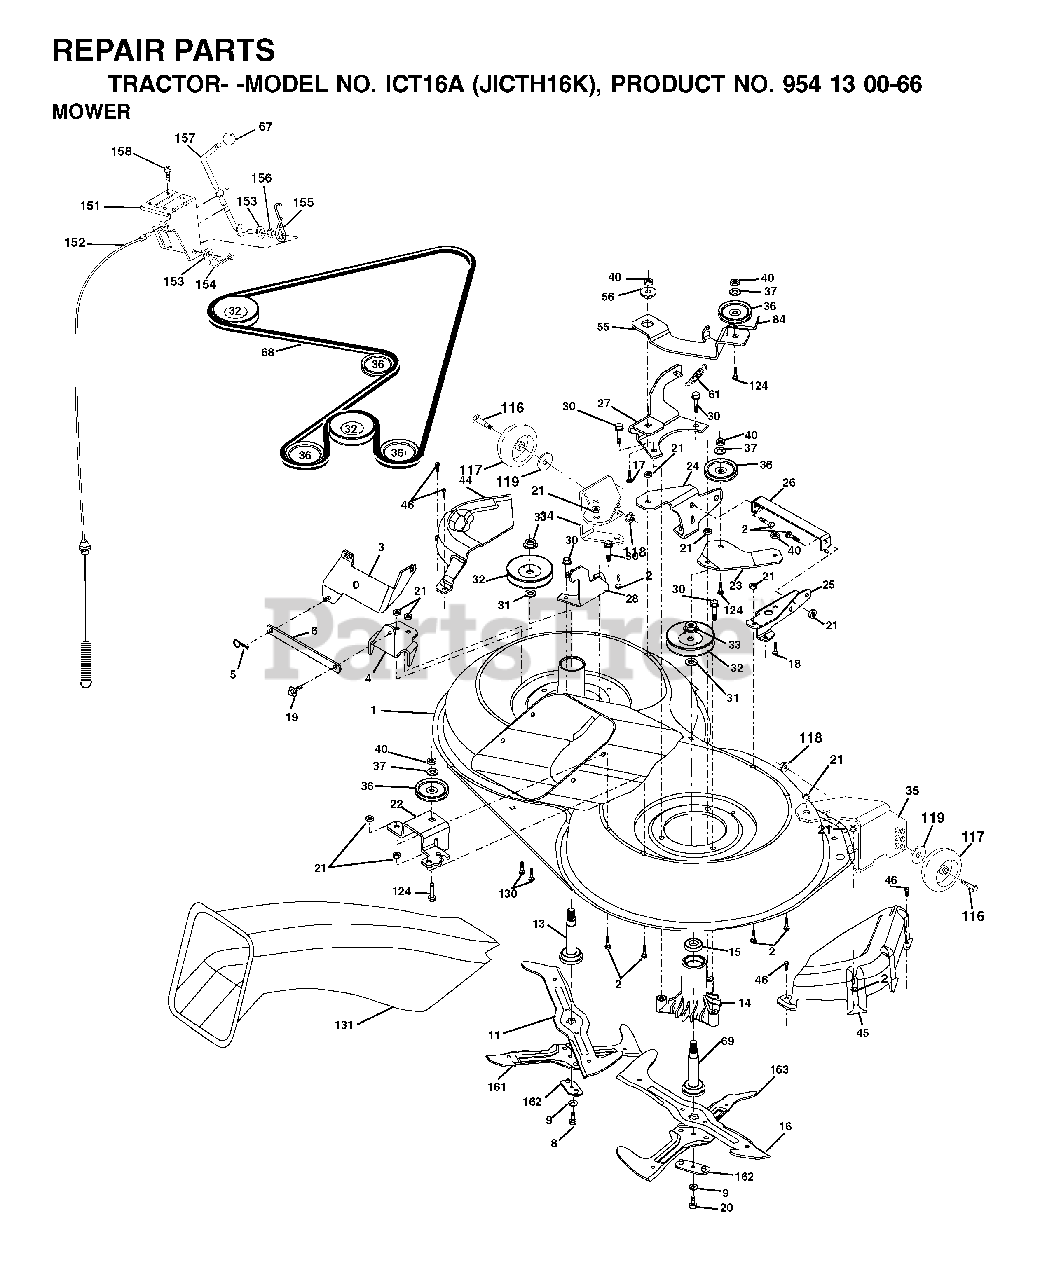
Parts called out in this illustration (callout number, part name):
1	MOWER HOUSING, DECK
2	BOLT
3	BRACKET
5	RETAINER-SPRNG RB
6	BAR SWAY
9	LOCKWASHER
10	WASHER.BLADE
11	BLADE-LH 5PT STAR(CTH130)
13	SHAFT ASM VENT
14	HSG MANDREL
16	BLADE RH 6PT STAR(CTH130)
17	BOLT.3/8-14X1.25
19	BOLT SHD 5/16-18
21	LOCKNUT
24	BRACKET
25	BRACKET
26	BRACE
28	BRACKET
30	SCREW, WASHER HEAD
31	WASHER
32	PULLEY, MANDREL
33	NUT, FLG TOPLOCK 9/16"
36	PULLEY.IDLER.4.25
40	LOCKNUT
45	MANDREL COVER
46	SCREW.1/4-20X5/8
55	ARM IDLER
56	SPACER.RETAINER.MOWER
61	SPRING.TENSION.BELT
67	KNOB T (3/8 HOLE)
68	HEX-BELT
69	SHAFT.ASM.W/LWR.BRG.RH.THREAD
84	KEEPER, BELT IDLER
116	BOLT, SHOULDER
117	WHEEL GAGE DONUT
118	LOCKNUT
119	WASHER
124	BOLT.3/8-16X1.50
131	CHUTE BAGGER
151	BRACKET, CLUTCH CABLE
153	WASHER FLAT 3/8"
154	SPRING RETAINER
155	SPRING RETENTION LEVER
156	SPACER CLUTCH CABLE
157	ROD CLUTCH CABLE 3/8"
158	SCREW
